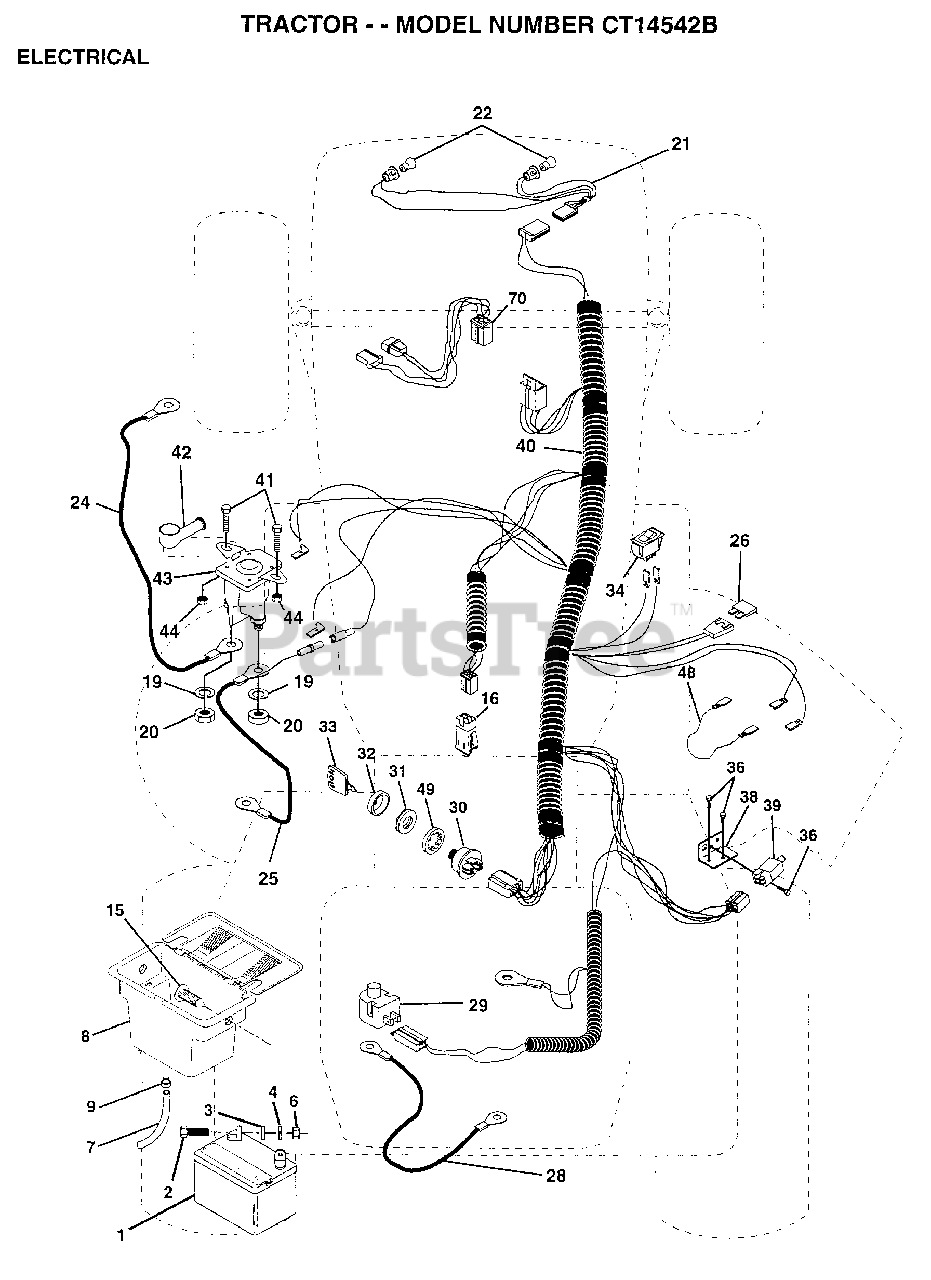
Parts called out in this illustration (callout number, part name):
2	BOLT LT
3	WASHER
4	LOCKWASHER
7	TUBE T
9	HOSE CLAMP T
15	FASTNER.SNAP-IN
16	SWITCH INTERLOCK
20	NUT
21	"HARNESS,LIGHT SOC"
22	HEADLAMP BULB
24	CABLE.BTRY.6GA.RD
25	CABLE.BTRY.6GA.38
26	FUSE HYT
28	CABLE T
29	SWITCH SEAT
32	COVER KEY SWITCH
33	KEY MLD GEN DELTA
34	SWITCH LT
36	SCREW
38	BRACKET SWITCH IN
39	SWITCH INTERLOCKT
40	HARNESS.IGN.DASH.
41	BOLT HXHD FIN
44	NUT HXKEP 1/4X20
45	ADAPTER AMMETER
49	WASHER PINNED
70	HARNESS.ENG.DUAL
